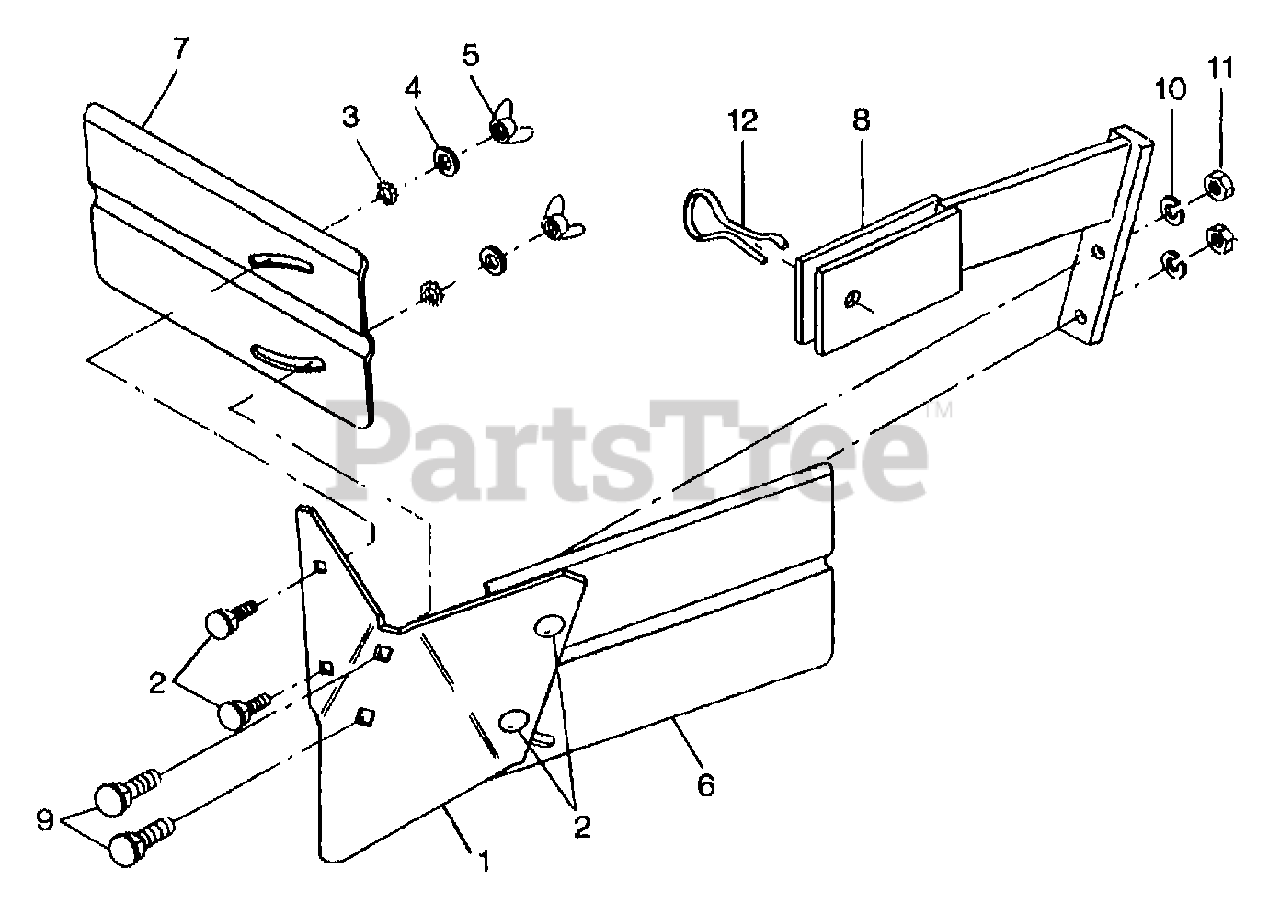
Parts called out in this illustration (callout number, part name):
1	BLADE-FURROWER PNT
2	SCR-CARR 5/16-18X.75 G2 ZP
3	WASHER-LK .312 EXT TOOTH
4	WASHER-FLAT 5/16 SAE
5	NUT-WING/LK 5/16-18 ZP
6	WING-HILLER LEFT PNT
7	WING-HILLER RIGHT PNT
8	BRKT-H/F PNT
9	BOLT-CARR 3/8-16X1.5 ZP
10	WASHER-LK .375 @ DEPL
11	NUT-HEX 3/8-16 ZP
12	PIN-CLINCH .312DIA ZP
